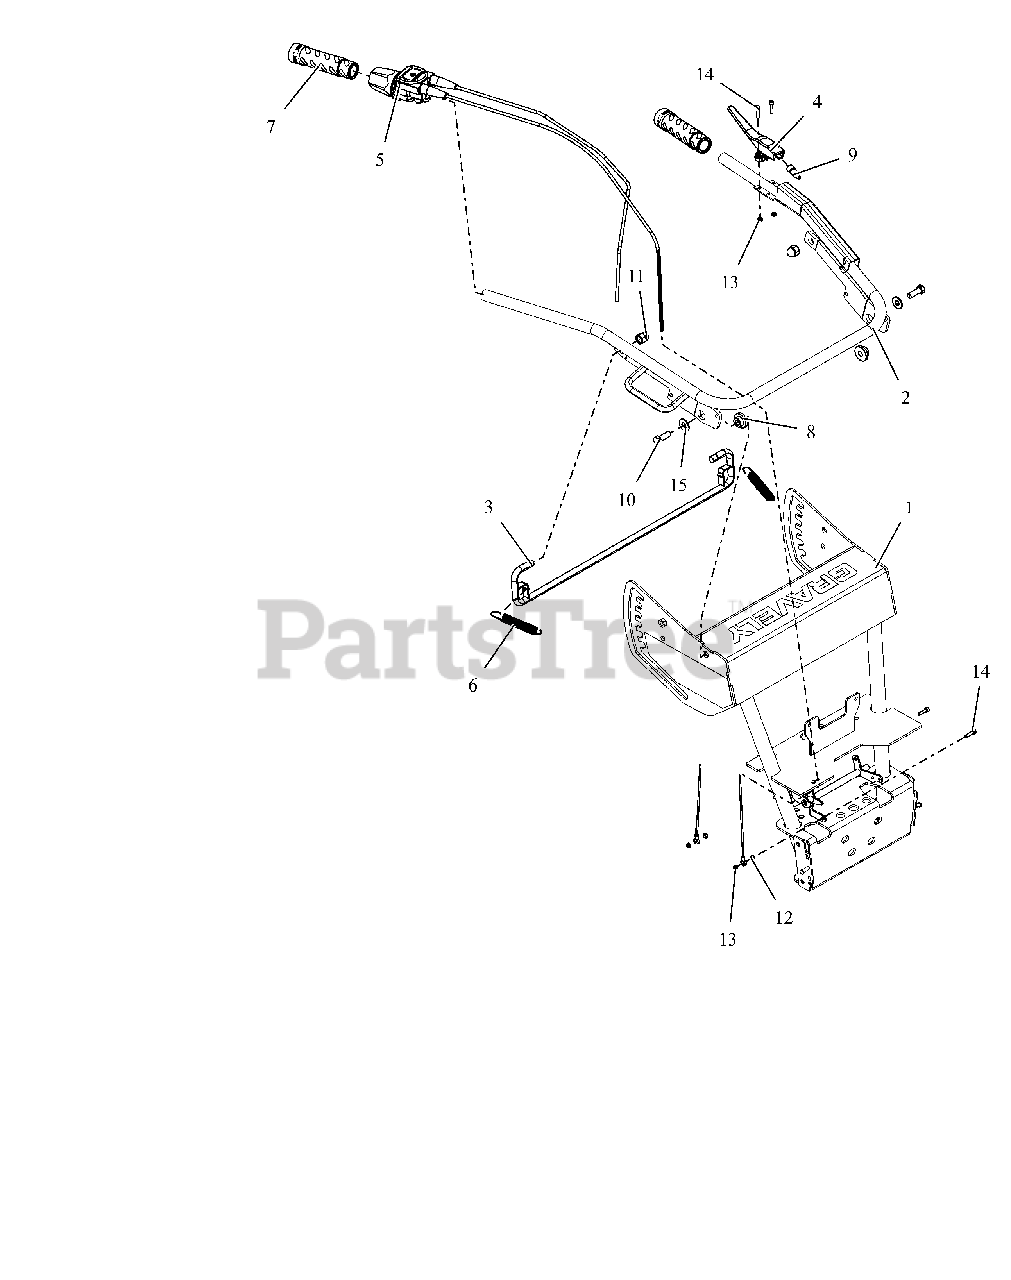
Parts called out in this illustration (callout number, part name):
1	ASM, STEERING PIVOT W/DECALS
2	WLDMT, HANDLEBAR ADJUSTABLE
3	WLDMT, LEVER HANDLEBAR ADJUST
4	ASM, LEVER OP PRESENCE
5	ASM, TWIST GRIP W/CABLE
6	SPRG, EXT .653 X .063 X 2.755
7	RUBBER, HANDLE
8	BSHG, STEP .413X.776X1.25X.413
9	BOOT, OPC
10	BLT, HEX M10-1.5 X 30 G8.8 ZCC
11	M12-1.75 ACORN NUT BLACK ZINC
12	NUT, HEX M5-.8 G8.8 ZCC
13	NUT,NYL M5-.8 G8.8 ZCC
14	SCR, SKH M5-.8X20 12.9ZC120
15	WSHR,FLT .438X1.00X.083 ZCC
